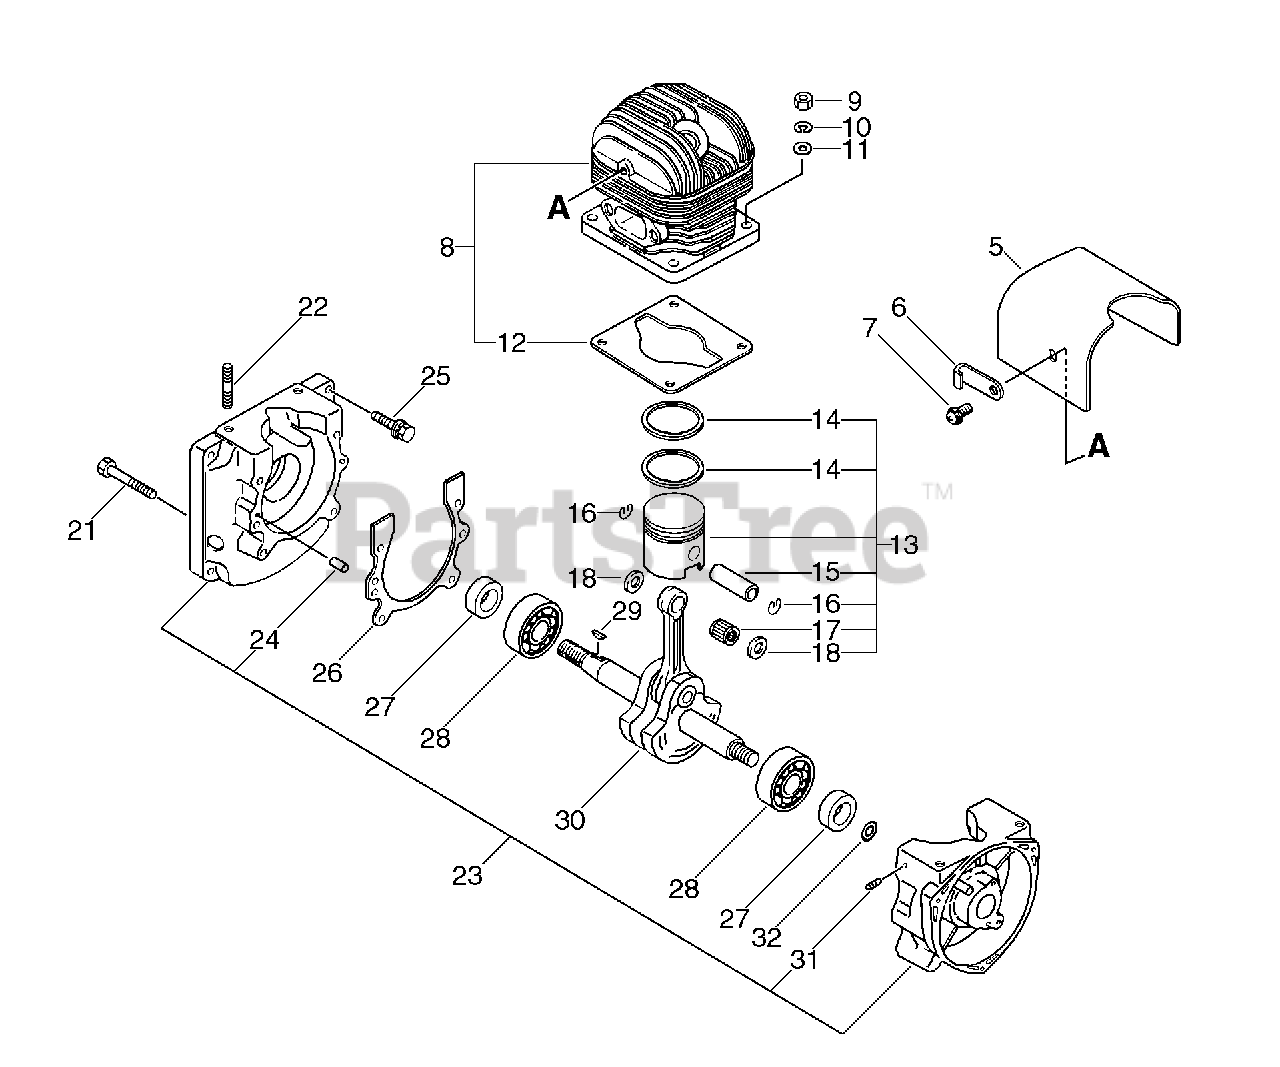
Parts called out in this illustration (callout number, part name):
5	COVER, CYLINDER
6	CLIP, CORD
7	BOLT 6×10
8	CYLINDER KIT
9	NUT, HEX M6
10	WASHER, SPRING 6
11	WASHER 6.5×11.5×0.8
12	GASKET, CYLINDER
13	PISTON KIT
14	RING, PISTON
15	PIN, PISTON
16	RING, SNAP 8
17	BEARING, NEEDLE 10
18	WASHER, THRUST
23	CRANKCASE KIT
24	PIN, LOCATING 5×10
27	SEAL, OIL
28	BEARING, BALL
30	CRANKSHAFT ASSY
31	CONNECTOR
32	WASHER PB-400
